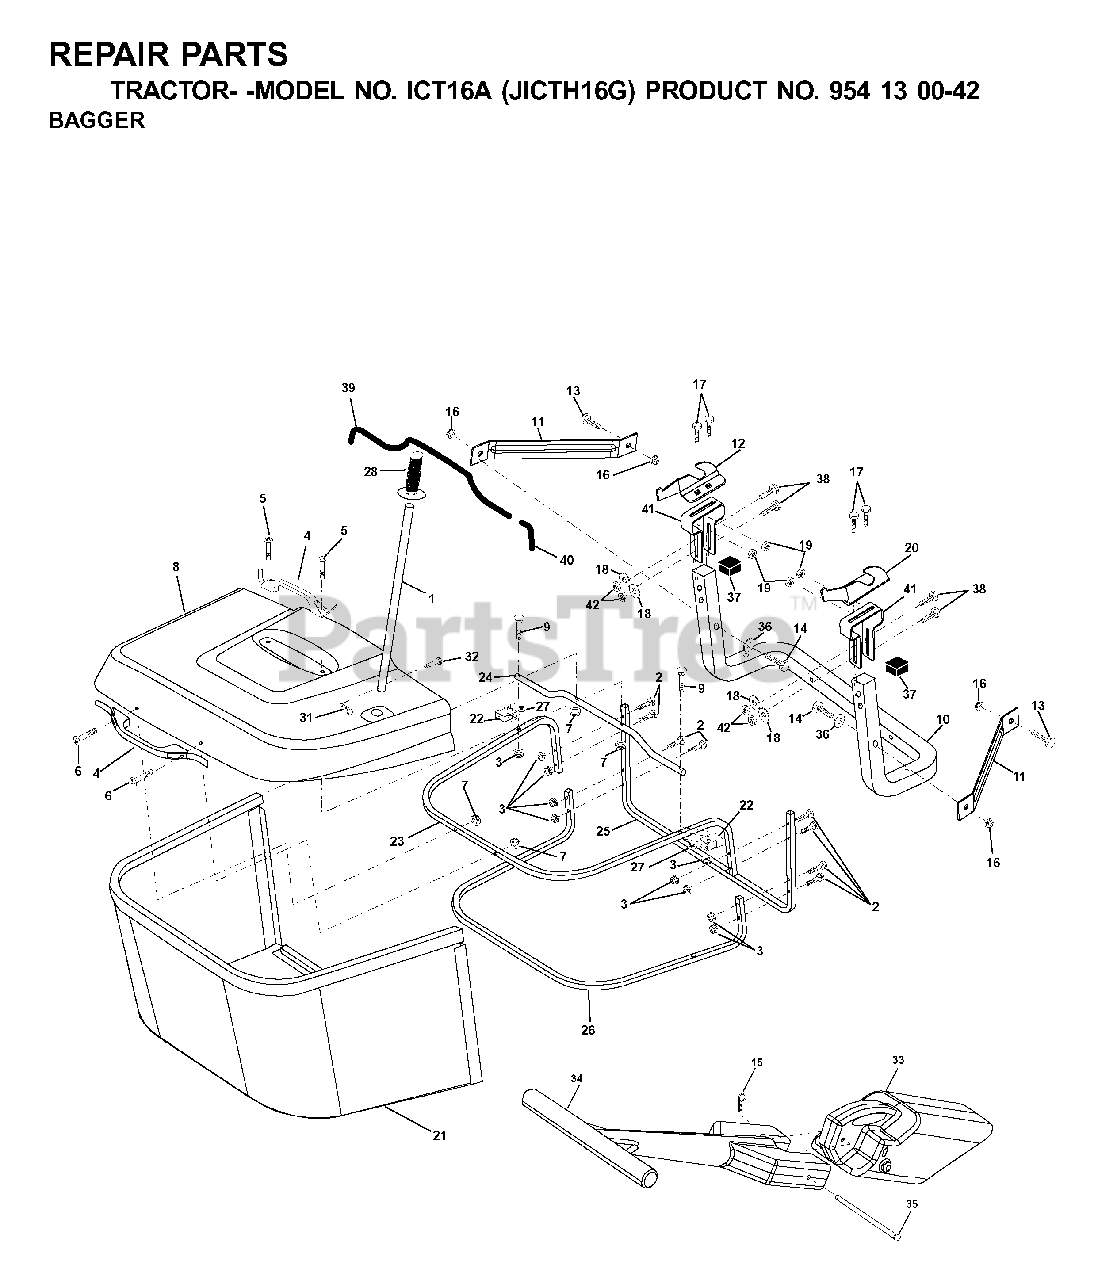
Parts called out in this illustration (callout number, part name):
1	TUBE HANDLE BAGGER
3	NUT T
5	SCREW.PAN.HEAD
10	TUBE
11	BRACKET
15	RETAINER-SPRNG RB
16	NUT LOCK FLG 3/8-16 UNC
17	BOLT
18	WASHER M
19	NUT LOCK HEX FLANGE 5/16-18
20	BRACKET
21	BAG
22	BRACKET
23	TUBE
24	TUBE
26	TUBE
31	RETAINER M
32	RIVET,DRILLED
33	MULCH PLUG, CTH150
35	PIN
36	WASHER
38	BOLT.5/16-18X2.5
39	TRIM
40	TRIM
41	BRKT, BAGGER
42	NUT.71038.31-18.HEX.NYLOCK
